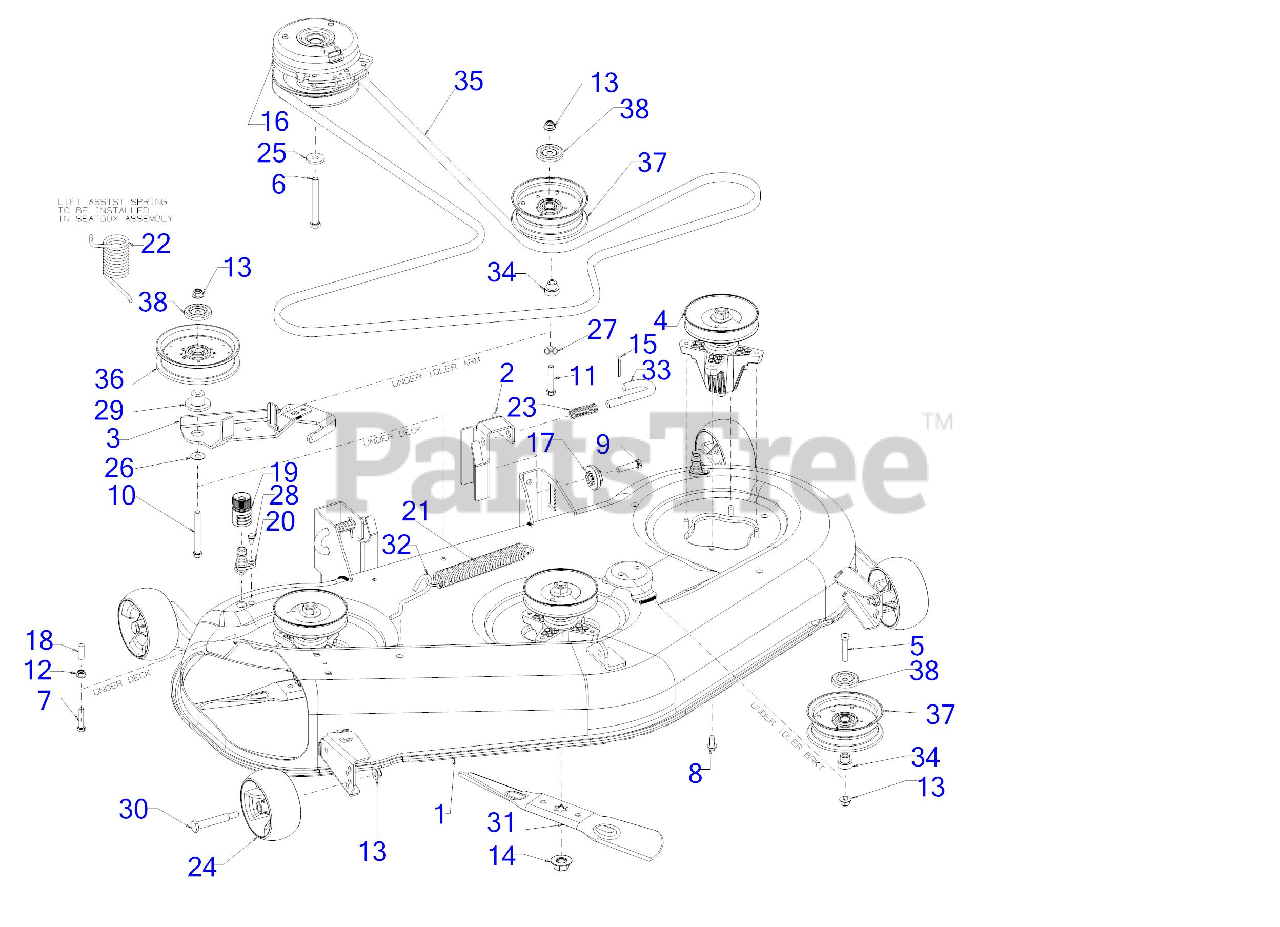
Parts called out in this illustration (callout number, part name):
1	50" DECK SHELL
4	SPINDLE ASSEMBLY
5	HEX SCREW 3/8-16 x 1.75 GR5
6	SCREW 7/16-20 x 3.5 GR5
7	SCREW 5/16-18 x 1.5 LG
8	SCREW 5/16-18 x .750
9	SCREW 3/8-16X1.5 GR5
10	SCREW 3/8-16 x 3.25 GR8
11	SCREW 3/8-16 x 2.0 GR5
12	FLANGE LOCK NUT 5/16-18
15	COTTER PIN-5/32 DIA
16	ELECTRIC PTO CLUTCH
17	DECK ADJUSTMENT GEAR
19	WATER NOZZLE
20	DECK WASH NOZZLE
21	EXTENSION SPRING
22	TORSION SPRING
23	COMPRESSION SPRING
24	DECK WHEEL
25	FLAT WASHER .445 x 1.248 x .170
26	FLAT WASHER
28	SHOULDER SCREW 1/4-20 x .50
29	SHOULDER SPACER
30	SHOULDER BOLT
31	17.27" BLADE (2N1)
32	DECK SPRING HOOK
33	DECK RELEASE PIN
34	SHOULDER SPACER
35	V-BELT B SEC x 143.5 LG
36	FLAT IDLER PULLEY
37	IDLER PULLEY 4.50" DIA
38	IDLER PULLEY CAP
